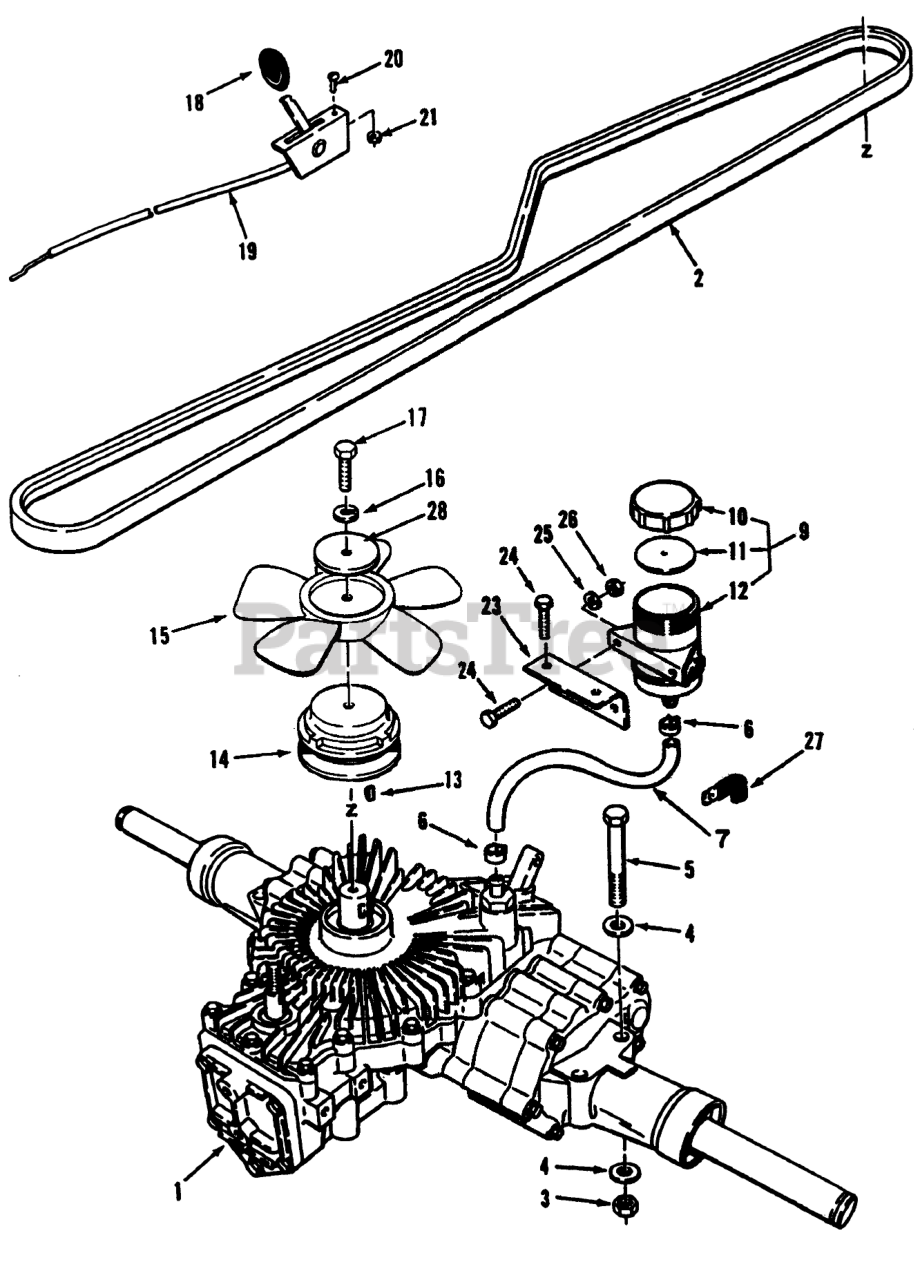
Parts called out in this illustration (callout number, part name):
1	TRANSAXLE "L" HYDRO
2	BELT V
3	NUT-LOCK, NI
4	WASHER-PLAIN
5	SCREW-HH
6	CLAMP .875
9	Reservoir Assembly (Incl. Ref. #10-12)
10	COVER
11	COVER GASKET
12	RESERVOIR
13	HARD HI PRO KEY
14	PULLEY-HYDRO
15	BLADE-FAN
16	WASHER
17	Bolt
19	CABLE-PUSH VALVE
20	Screw
21	Nut
23	BRKT-RESERVOIR MT R
24	SCREW-HH
25	WASHER-FLAT
26	NUT-LOCK, NI
27	CLIP
28	WASHER
